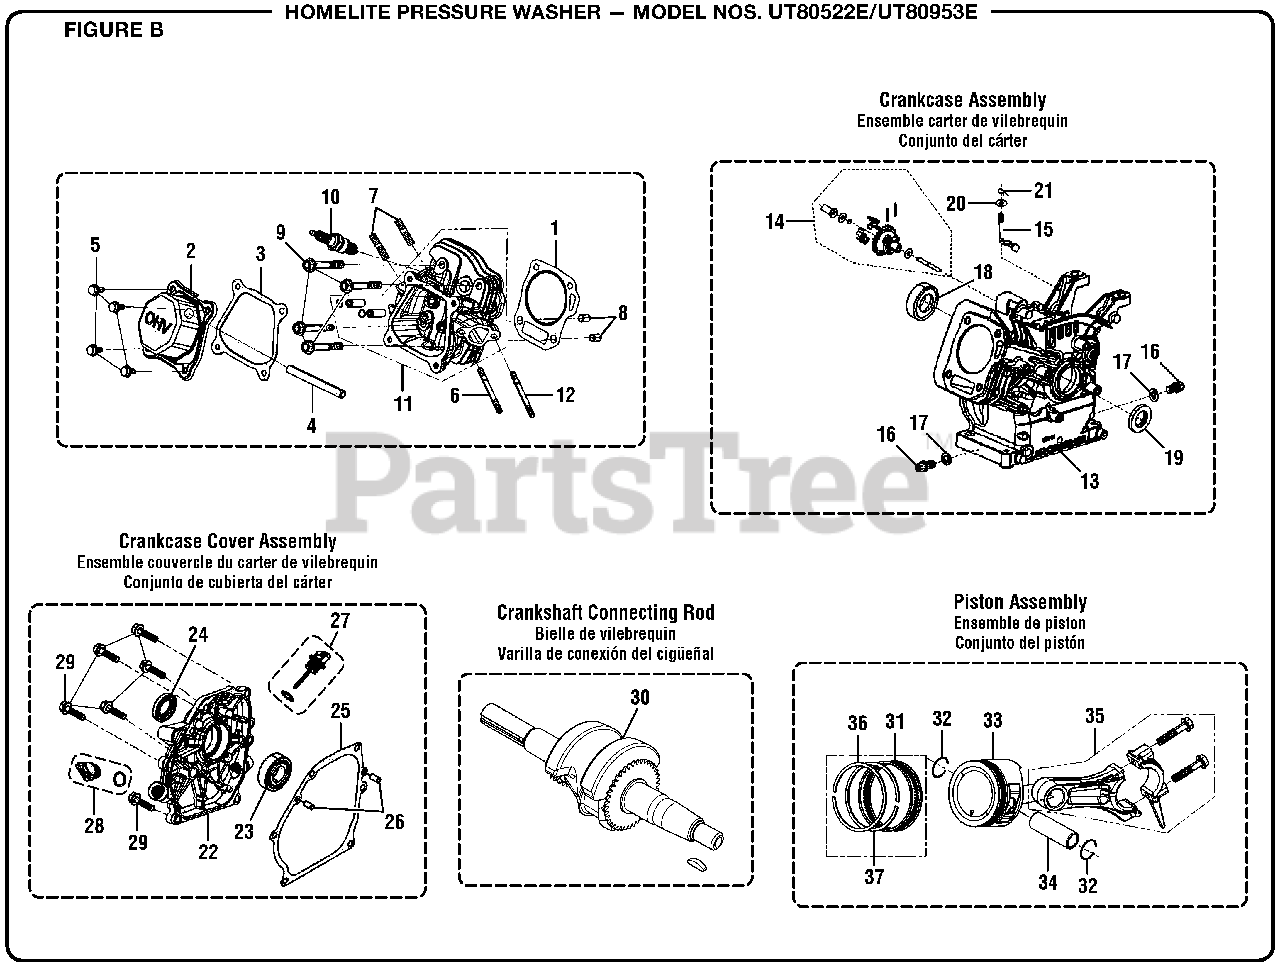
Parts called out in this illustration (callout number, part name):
1	Cylinder Head Gasket
2	Cylinder Head Cover
3	Cylinder Head Cover Gasket
9	Cylinder Head Bolt
11	Cylinder Head Assembly
13	Crankcase Assembly
14	Governor Gear Assembly
18	Ball Bearing
22	Crankcase Cover Assembly
23	Ball Bearing
25	Crankcase Gasket
27	Oil Dipstick Assembly
28	Oil Cap Assembly
30	Crankshaft Assembly
32	Piston Pin Clip
33	Piston Assembly
37	The Second Ring
